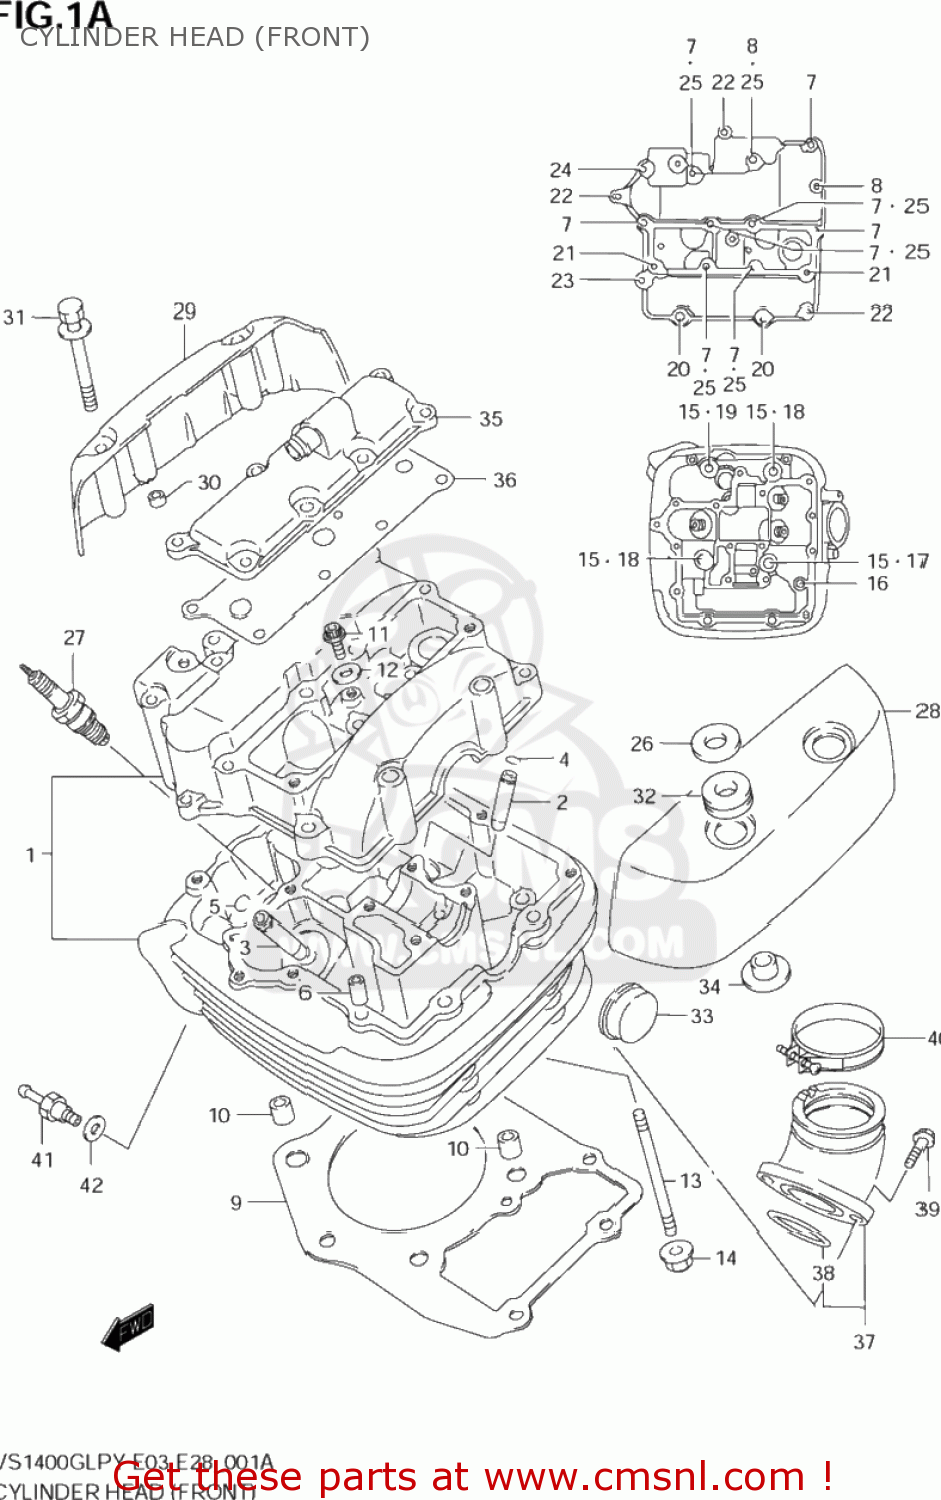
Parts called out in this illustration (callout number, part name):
1	HEAD ASSY,CYLINDER FR
2	GUIDE,INTAKE VALVE
3	GUIDE,INTAKE VALVE
4	RING,SNAP
5	RING,SNAP
6	PIN(6.2X8X11)
7	BOLT(6X60)
8	BOLT(6X55)
9	GASKET,CYLINDER HEAD FR (NAS)
10	PIN
11	BOLT
12	GASKET(6.2X13X1.2) (NAS)
13	BOLT,STUD
14	NUT
15	WASHER(10.5X22X2.3)
16	BOLT(8X70)
17	BOLT(10X180)
18	BOLT(10X190)
19	BOLT(10X200)
20	BOLT(8X268)
21	BOLT
22	BOLT
23	BOLT
24	BOLT
25	GASKET(5.8X13X1.2) (NAS)
26	WASHER(8.5X24X1.6)
27	SPARK PLUG DP7EA-9
28	CAP,CYLINDER HEAD COVER FL
29	CAP,CYLINDER HEAD COVER FR
30	CUSHION,R CAP
31	BOLT
32	CUSHION
33	PLUG(OD:30)
34	BUSH
35	COVER,BREATHER
36	GASKET,BREATHER COVER (NAS)
37	PIPE ASSY,INTAKE FR
38	O RING(D:2.4,ID:41.7)
39	BOLT
40	CLAMP
41	BOLT UNION
42	GASKET(6.2X13X1.2) (NAS)
